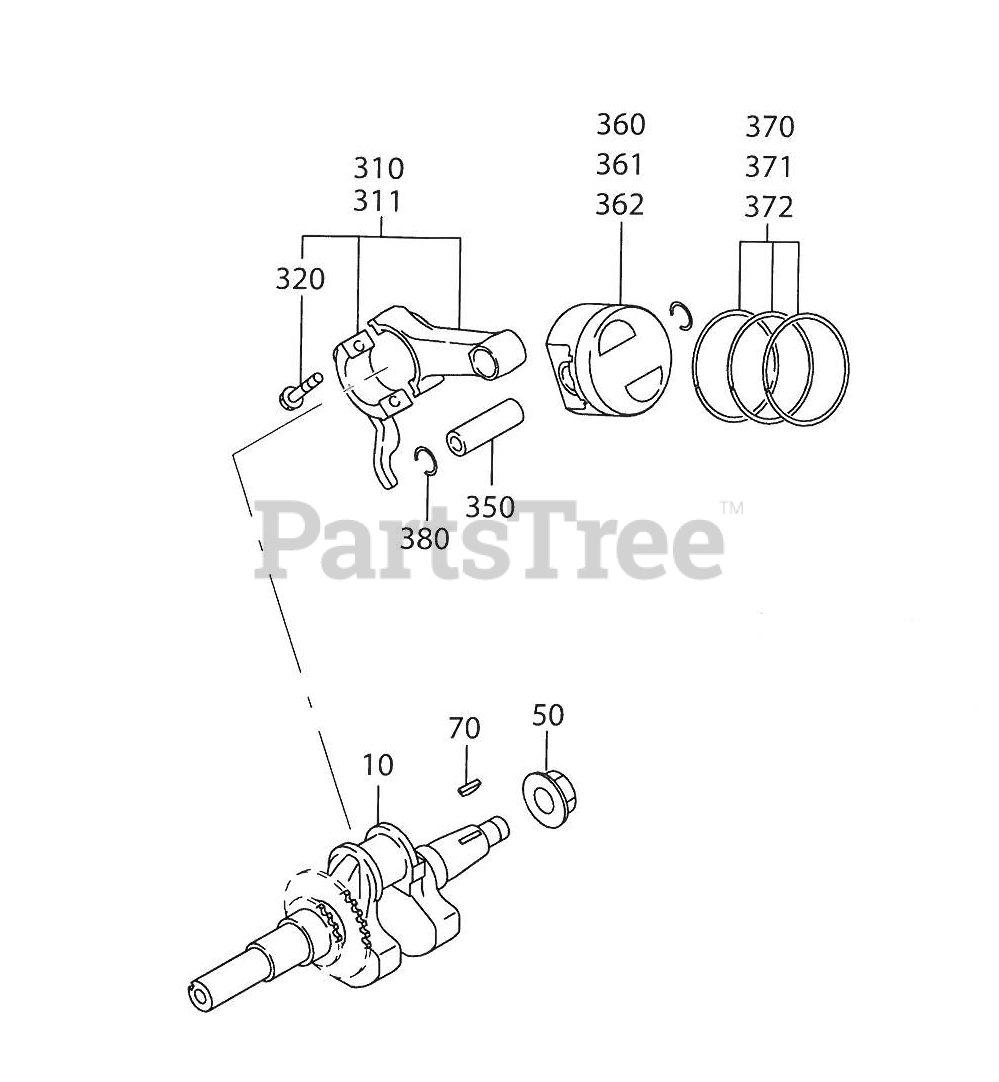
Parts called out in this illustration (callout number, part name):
310	CONNECTING ROD AY
320	CONNECTING ROD BOLT
370	PISTON RING SET
371	PISTON RING SET
372	PISTON RING SET
